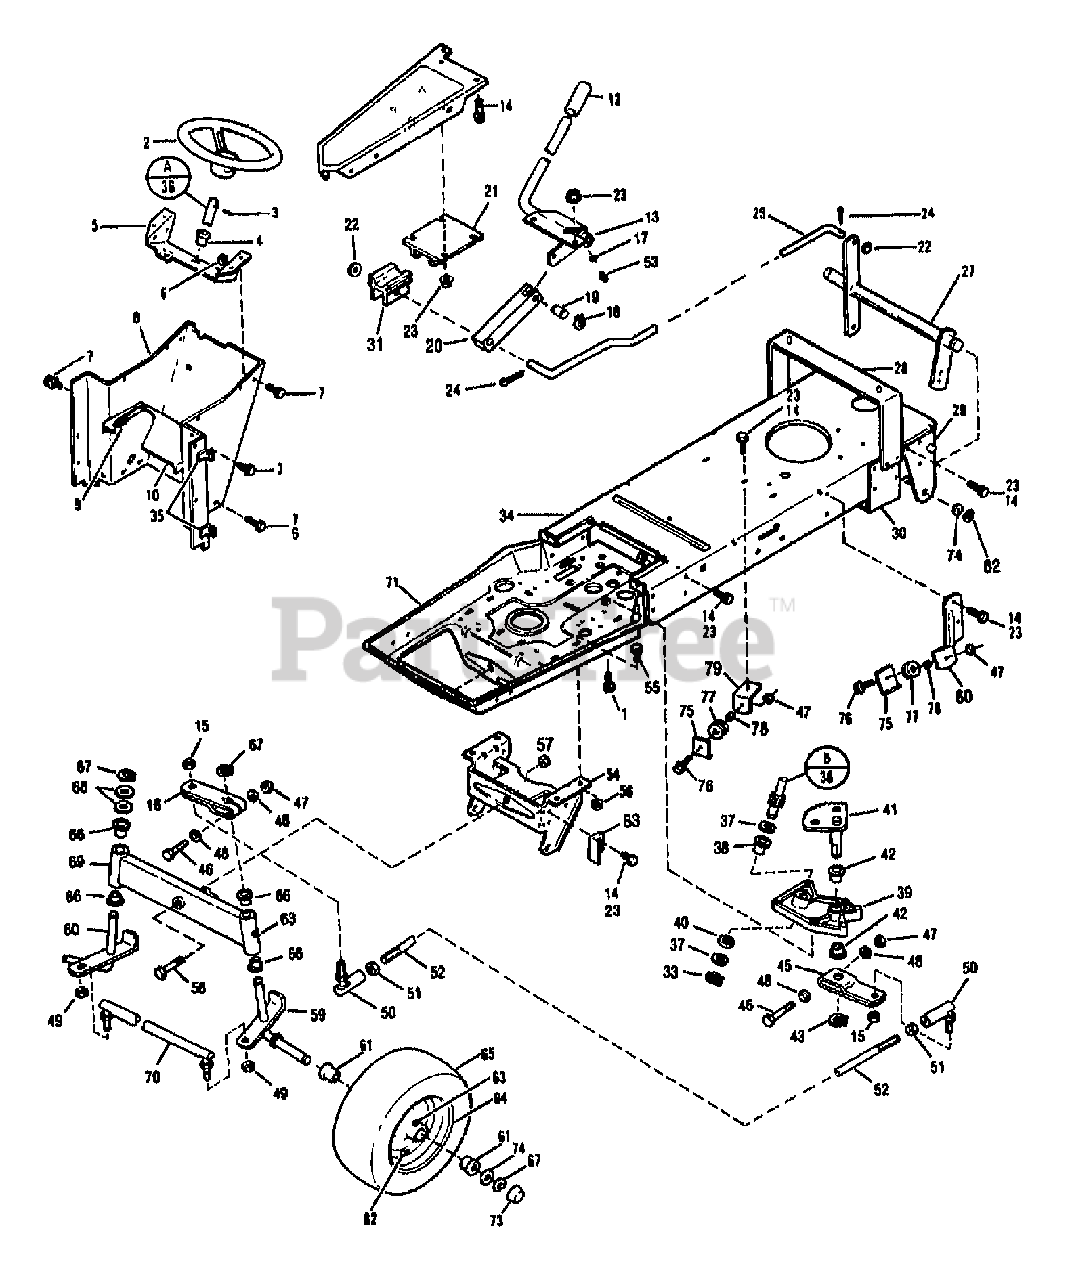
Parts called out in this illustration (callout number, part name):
1	SCR-HFLK 5/16-18X.75
2	WHEEL-STEERING
3	PIN-ROLL .25X2.25
4	BEARING-FLANGED NYLON
5	SUPPORT-STEERING SHAFT
6	NUT-HF/LK 1/4-20 ZP
7	SCR-HH 1/4-20X.625
8	SUPT-INSTRUMENT PANEL
9	NUT-SPEED
10	SUPPORT-BATTERY
12	GRIP-FLEX
13	ASSM-LIFT LEVER
14	SCR-LOCK
15	NUT-HEX/JAM 1/2-20 ZP
16	ASSM-ARM SPINDLE
17	WASHER
18	RING-RETAINING
20	LINK-PUSH
21	GUIDE-STAT
22	WASHER-1.06X.531X.1 ZP
23	NUT-HFLK 5/16-18 ZP
24	PIN-COTTER .120X1.00 ZP
25	ROD-LIFT
27	ASSM-LIFT SHAFT
28	ASSM-FENDER SUPPORT
29	ASSM-PANEL REAR
30	AXLE-SUPPORT
31	GUIDE-SLIDE
33	RING-RETAINING
35	NUT-SPEED
36	SHIFT-STEER
37	WASHER-SHIM
38	BEARING
39	ASSM-STEER SUPT
40	WASHER-1.115X.637X.06
41	ASSM-SECTOR GEAR
42	BEARING-FLANGE
43	RING-RETAIN EXT .707 ID
45	ASSM-ARM SPINDLE
46	SCR-HH 3/8-16X2.25 G5 ZP
47	NUT-LOCK 3/8-16
48	WASHER-.875X.390X.134
49	NUT-LOCK
50	JOINT-BALL
51	NUT-JAM
52	ROD-STEERING
53	FITTING-GREASE
54	BRKT-ATTACHMENT
56	NUT-HFLK 3/8-16 ZP
57	NUT-H/LK 5/8-11
58	SCR-HH 5/8-11X2.25 G5 ZP
59	ASSM-SPINDLE LH
60	ASSM-SPINDLE RH
61	BUSHING
62	STEM-VALVE
63	FITTING-GREASE 1/4-28X2.00
64	WHEEL-RED
65	TIRE 15X6.00-6RS
66	BUSHING
67	RING-RET."E".577 ID
68	WASHER-1.25X.765X.049
69	ASSM-FRONT AXLE
70	ROD-TIE
71	FRAME-FRONT
73	CAP-DUST
74	WASHER-1.38 X.765X .06 ZP
75	GUIDE-CABLE
76	SCR-HH 3/8-16X1.25
77	PULLEY-CABLE
79	BRACKET
83	BRACKET
